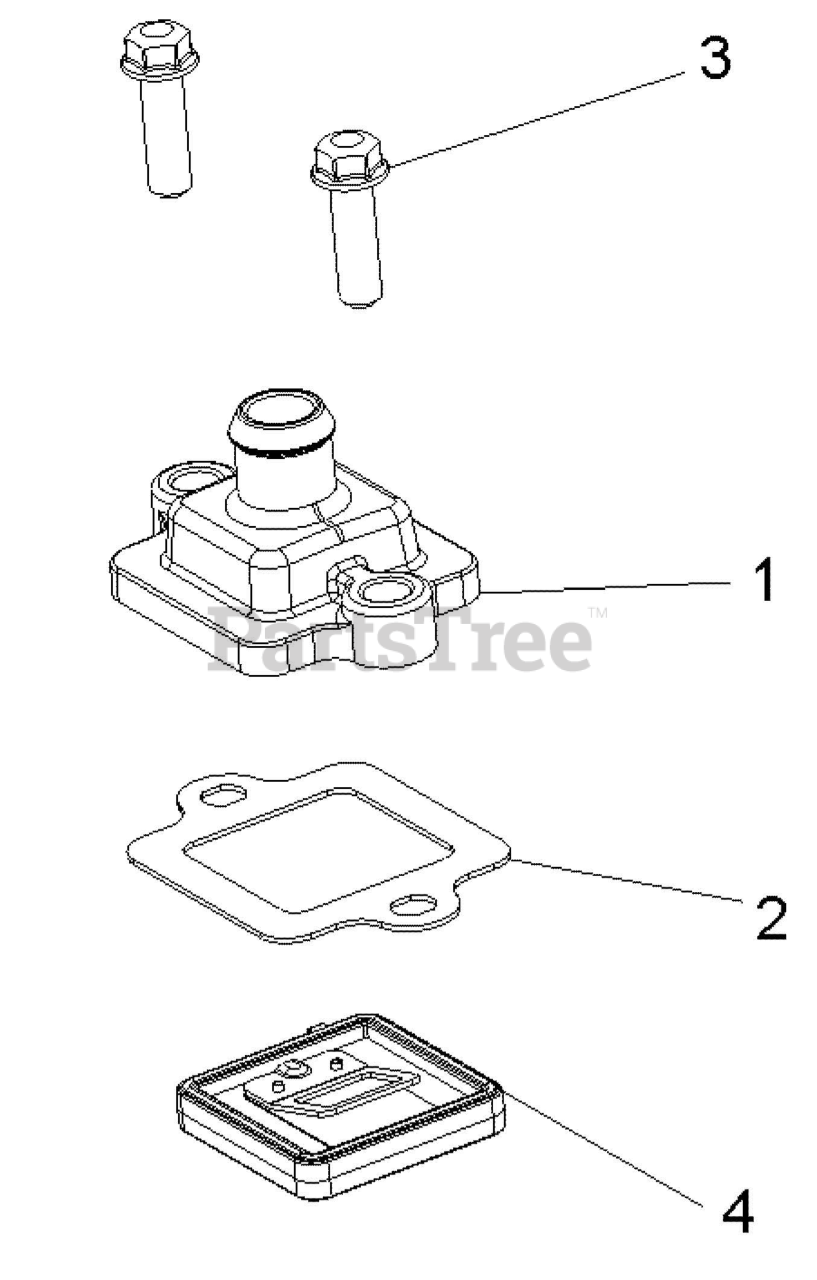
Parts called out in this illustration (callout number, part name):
1	COVER-BREATHER,MACH
2	GASKET-BREATHER,COVER
3	SCR-M6X20,HXFLG,0600214
4	ASM-REED W/GASKET
